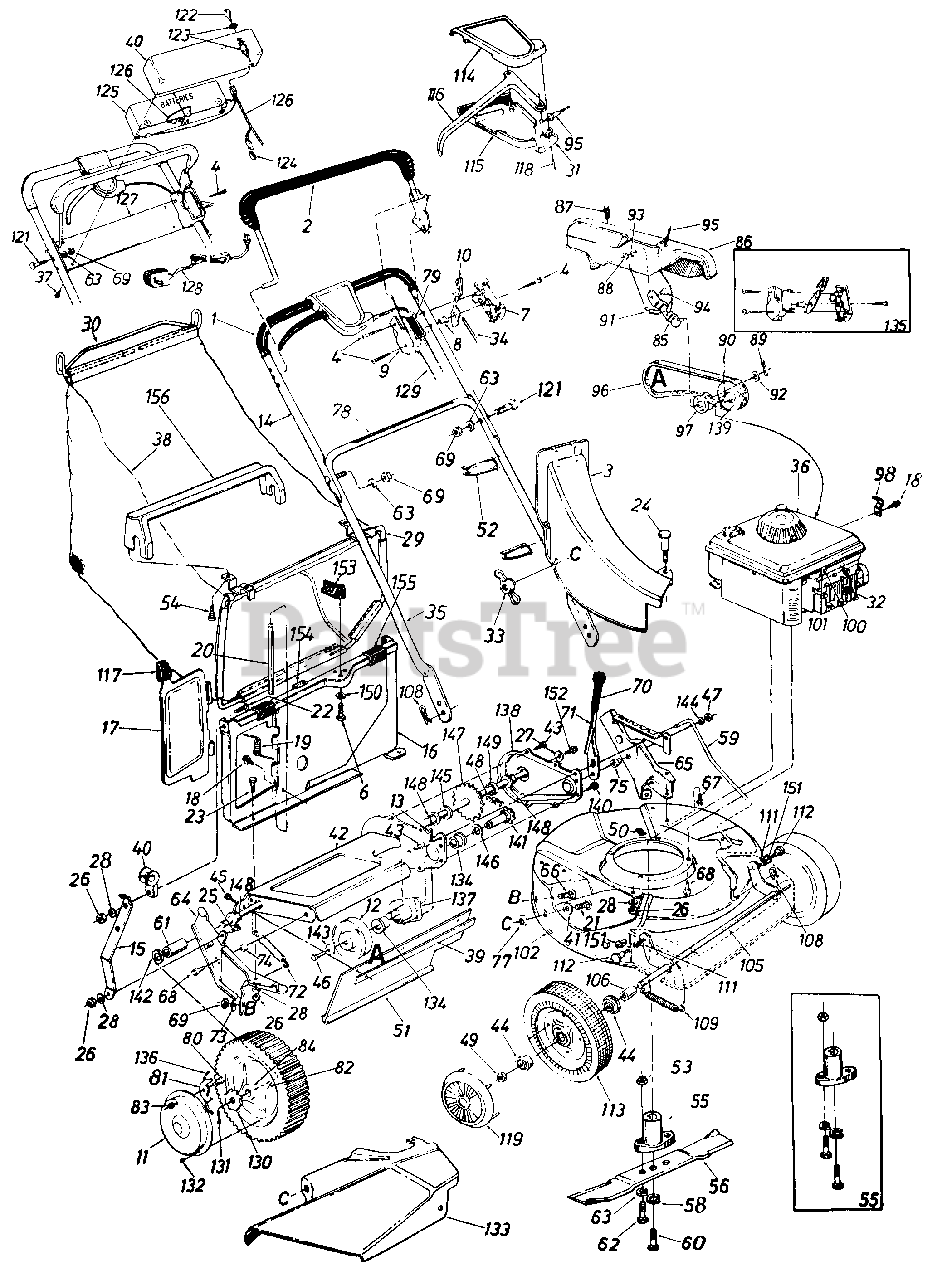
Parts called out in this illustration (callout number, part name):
2	Control Handle Assembly
3	Top Discharge Chute Assembly
4	Truss Machine Screw #12 x 1.5"
6	Hex Bolt 1/4-20 x .62"
7	Control Panel Half
8	Control Disc Pin
9	Clutch Panel Half
10	Throttle Control Lever
11	Hub Cap
12	1/2" V-Pulley
13	Cotter Pin 3/32" Diameter 75"
14	Upper Handle
15	Panel Support Bracket
16	Top Catcher Panel Assembly
17	Top Door
18	Hex B-Tap Screw .Y 10 x .38 "
19	Torsion Spring
20	Pivot Pin
21	Carriage Bolt 1/4-20 x . 62" *
22	Truss Machine Screw 1/4-20 x 3/4"
23	Hex Bolt 1/4-20 x .50"
24	Shoulder Bolt
25	Hex Bolt 1/4-20 x .62"*
26	Hex Nut 1/4-20 Thread*
27	Bellville Washer .280" I . D .
28	Lock Washer 1/4" I.D.*
29	Front Grass Catcher Frame
30	Grass Catcher Handle
31	Control Cover
32	Spark Plug Insulator
33	Wing Nut
34	Throttle Control Wire 58"
35	Lower Handle
36	Engine
37	Truss Self-Tap Screw 1" Long
38	21 " Top Discharge Grass Bag
39	Retaining Strip
40	Battery Tray
41	Flat Washer .344" I.D. x .62 "
42	Chain Axle Assembly
43	Hex B-Tap Screw 1/4" x .38 "
44	Flange Ball Bearing
45	Hex AB-Tap Screw 1/4 x .62"
46	Hex TT-Tap Screw 1/4-20
47	Hex Patch Lock Nut 3/8-24 Thread
48	#48 Chain .5" Pitch x .30 Links
49	Hex Lock Nut 1/2-20 Thread
51	Rear Flap
52	Cable Tie
53	Hex Nut 5/16-24 Thread
54	Truss Self-Tap Screw 1" Long
55	Blade Adapter Kit
56	21" Blade
58	L-Wash. 3/8" I.D.
59	Height Adjustment Rod
60	Hex Bolt 3/8-24 x 2 25" (Grade 5)
61	Spacer 51" I.D.
62	Hex Bolt 5/16-24 x 1.0" (Grade 5)
63	Lock Washer 5/16" I.D.
64	R.H. Handle Wheel Bracket Assembly
65	L.H. Handle Wheel Bracket Assembly
66	Carriage Bolt 5/16-18 x .62 "*
67	Hex B-Tap Screw 5/16-18
68	Hex TT-Tap Screw 3/8-16
69	Hex Nut 5/16-18 Thread *
71	Height Adjustment Lever
72	Extension Spring
73	Belleville Washer 5/16" I . D.
74	Spacer .385" I.D.
75	Shoulder Spacer
77	Bolt Retainer
78	Instruction Label
79	Control Label
80	Shoulder Bolt
81	Pawl
82	Rear Wheel Assembly Complete
83	Hex Lock Nut 1/4-20 Thread
84	Flange Ball Bearing
85	Belt Idler Bracket Assembly
86	Belt Cover
87	Hex Self-Tap Screw 1/4-20 x .50 "
88	Hex Nut 1/4-20 Thread*
89	Cotter Pin 1/8" Diameter x l.O"*
90	Spring Pin Spiral 3/16" Diameter
91	Extension Spring .33" O.D.
92	Flat Washer 531 " I.D.
93	Lock Washer 1/4" I.D *
94	Shoulder Bolt
95	Cable-53" Long
96	"V"-Belt
97	Flat Idler Pulley
98	Casing Clamp
100	Hex B-Tap Screw #10 x 62 "
101	Casing Clamp
106	Sleeve 526" I.D.
108	Internal Cotter Pin 5/16" Diameter
109	Extension Spring
111	Internal Lock Washer 3/8 I.D.
112	Shoulder Bolt
113	Front Wheel Assembly Complete
114	Self-Propelled Control Cover
115	Self-Propelled Control Cover
116	Control Lever
117	Door Grip
118	Counter Sunk Tap Screw #10 x 75"
119	Hub Cap-Plastic
121	Carriage Bolt 5/16-18 x 1.38 "
122	Ignition Key
123	Ignition Switch
124	Plug
125	Battery Pack
126	Wire Harness
127	Lower Battery Tray
128	Battery Charger
129	Control Cable 43"
130	Ratchet Wheel
131	Cotter Pin 1/8" Diameter x 1.0"
132	Pan Head Tap Screw #12 x .50"
133	Side Chute Deflector Assembly
134	Flange Bushing
135	Kit-Control Housing Complete
136	Spring Nylon
137	Bearing Hub Flange Assembly
138	Chain Cove
139	Engine Pulley 1/2"
140	Hex Self-Tap Screw 1/4-20 x .50"
141	Sprocket Shaft Assembly
142	Flat Washer .531 " I.D.
143	Belleville Washer .265" I D .
144	Flat Washer 385" I.D.
145	Flat Washer .51 " I.D
146	Flat Washer .62" I.D.
147	Rear Shaft Assembly
148	Hex Flange Bearing
149	Spacer .510" I.D.
150	Spring Washer .32" I.D.
151	Flanged Nyliner Bearing
152	Hex Bolt 1/4-20 x .62" (Grade 5)
153	Grass Catcher Locking Knob
154	Foam Strip
155	Panel Clip
156	Bag Handle
